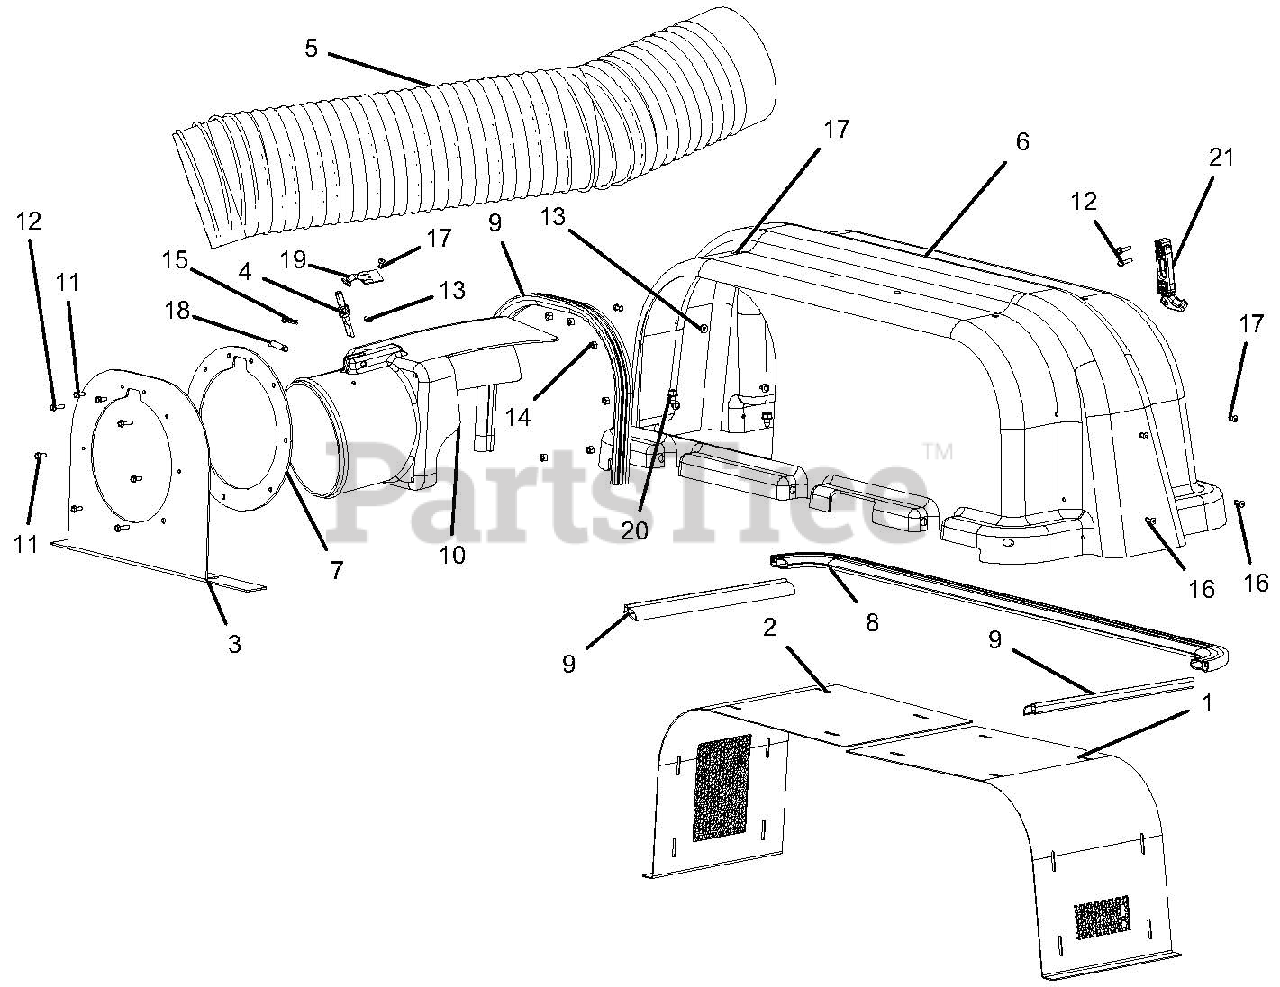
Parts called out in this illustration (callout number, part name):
1	WLDMT, BAGGER HOOD VENT, LH
2	WLDMT, BAGGER HOOD VENT, RH
3	WLDMT, TUBE SUPPORT
4	INDICATOR, FLOW
5	HOSE, FLEXIBLE-45"
6	COVER, 2-BUCKET BAGGER
7	SEAL, UPPER BOOT
8	SEAL, BULB - BAGGER HOOD
9	SEAL, BULB
10	BOOT, UPPER
11	@SCR-MCH 10-24X.50 HWH YWZC
12	@SCR-MCH 10-24X.75 HWH YWZC
13	WSHR-FL-STL.219X.500X.049YWZC
14	NUT-LK-NYL #10-24 YWZC
15	PIN-HAIR, ENDRIES #25 YWZC
16	RVT-POP .187x.684 DOME
17	RVT-POP .187x.527 DOME
18	PIN, CLEV .309X1.62 YWZC
19	LATCH, THUMB
20	SCR-TAP .31-18X.50 HWH TR YWZ
21	LATCH, RUBBER
